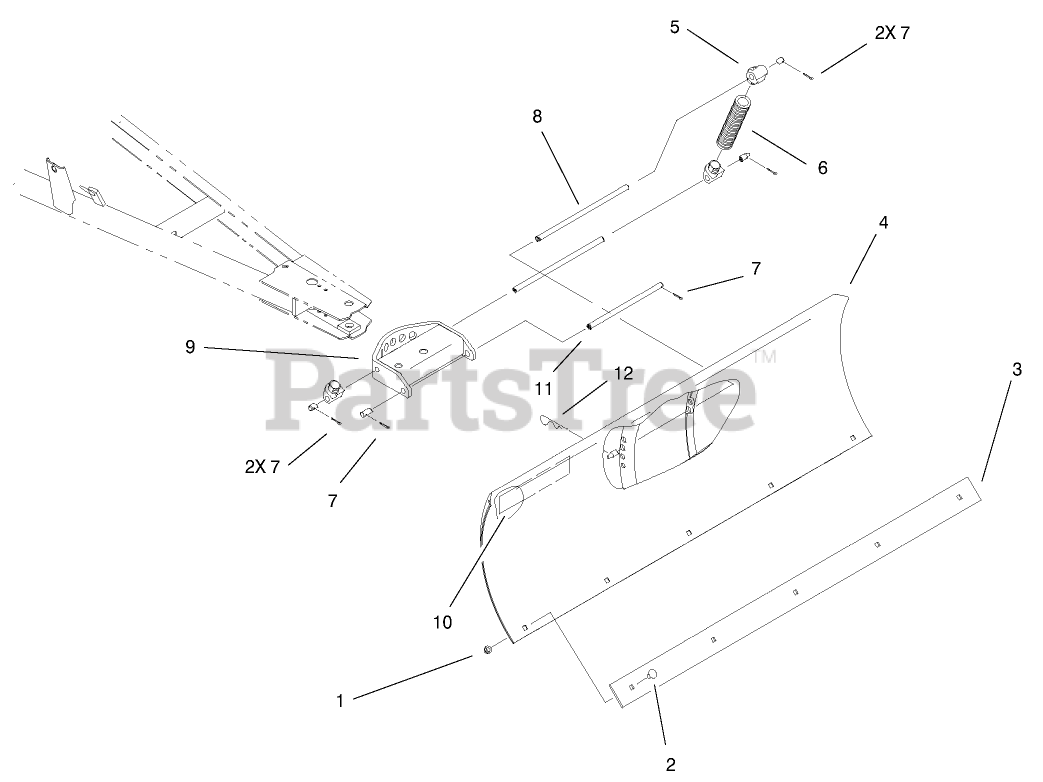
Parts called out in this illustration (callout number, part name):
1	NUT-LOCK, NI
2	SCREW-CARR
4	BLADE ASM
7	PIN-COTTER
8	ROD-PIVOT, BLADE
9	QUADRANT
11	ROD-LOWER
12	PIN-HAIR
